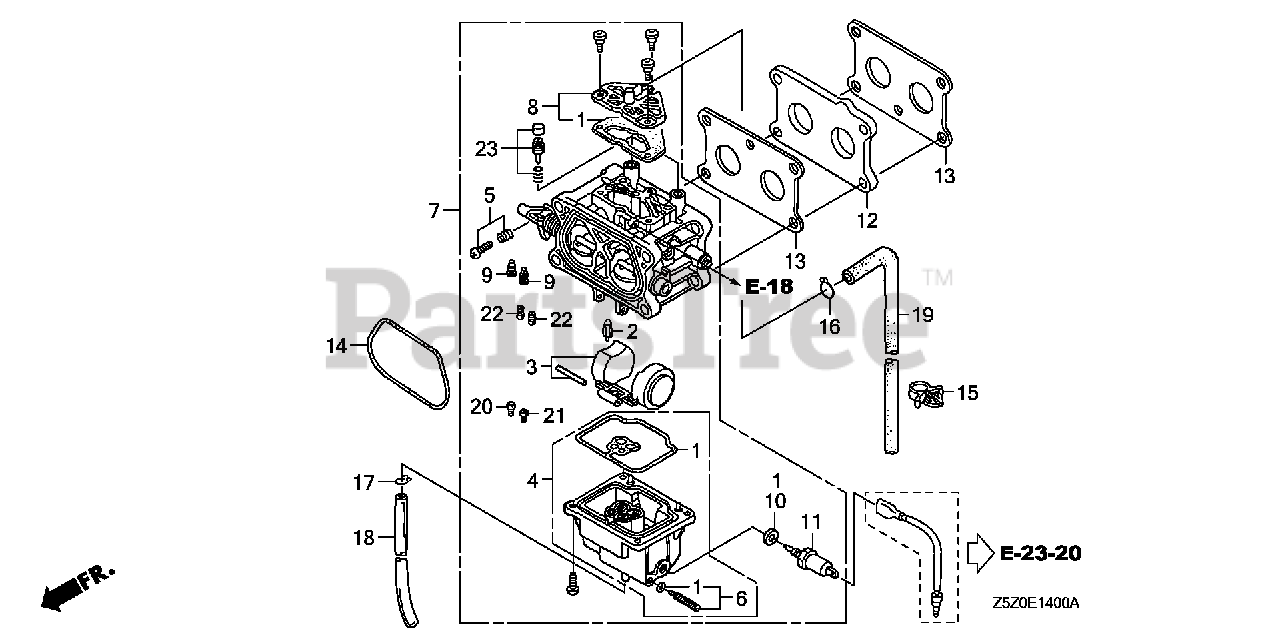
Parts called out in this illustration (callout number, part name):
1	GASKET SET
2	VALVE, FLOAT
4	CHAMBER SET, FLOAT
6	SCREW SET, DRAIN
7	CARBURETOR ASSY. (BW02B C)
8	COVER SET, AIR VENT
11	VALVE ASSY., SOLENOID
12	INSULATOR, CARBURETOR
13	GASKET, INSULATOR
14	GASKET, AIR CLEANER
15	CLIP, WIRE HARNESS
16	CLIP, TUBE (B8)
17	CLIP, TUBE (B6.5)
18	BULK HOSE, VINYL (4X7X8000) (95003-07(95003-07001-60M) (CARBURETOR NO.)
19	BULK HOSE, VACUUM (4.5X1000) (4.5X450) (BULK HOSE 95005-45008-10M)
20	JET, MAIN (#82.5)
20	JET, MAIN (#85)
20	JET, MAIN (#87.5)
21	JET, MAIN (#85)
21	JET, MAIN (#87.5)
21	JET, MAIN (#90)
22	JET, PILOT (#37.5) (CARBURETOR NO.)
23	SCREW SET, PILOT
